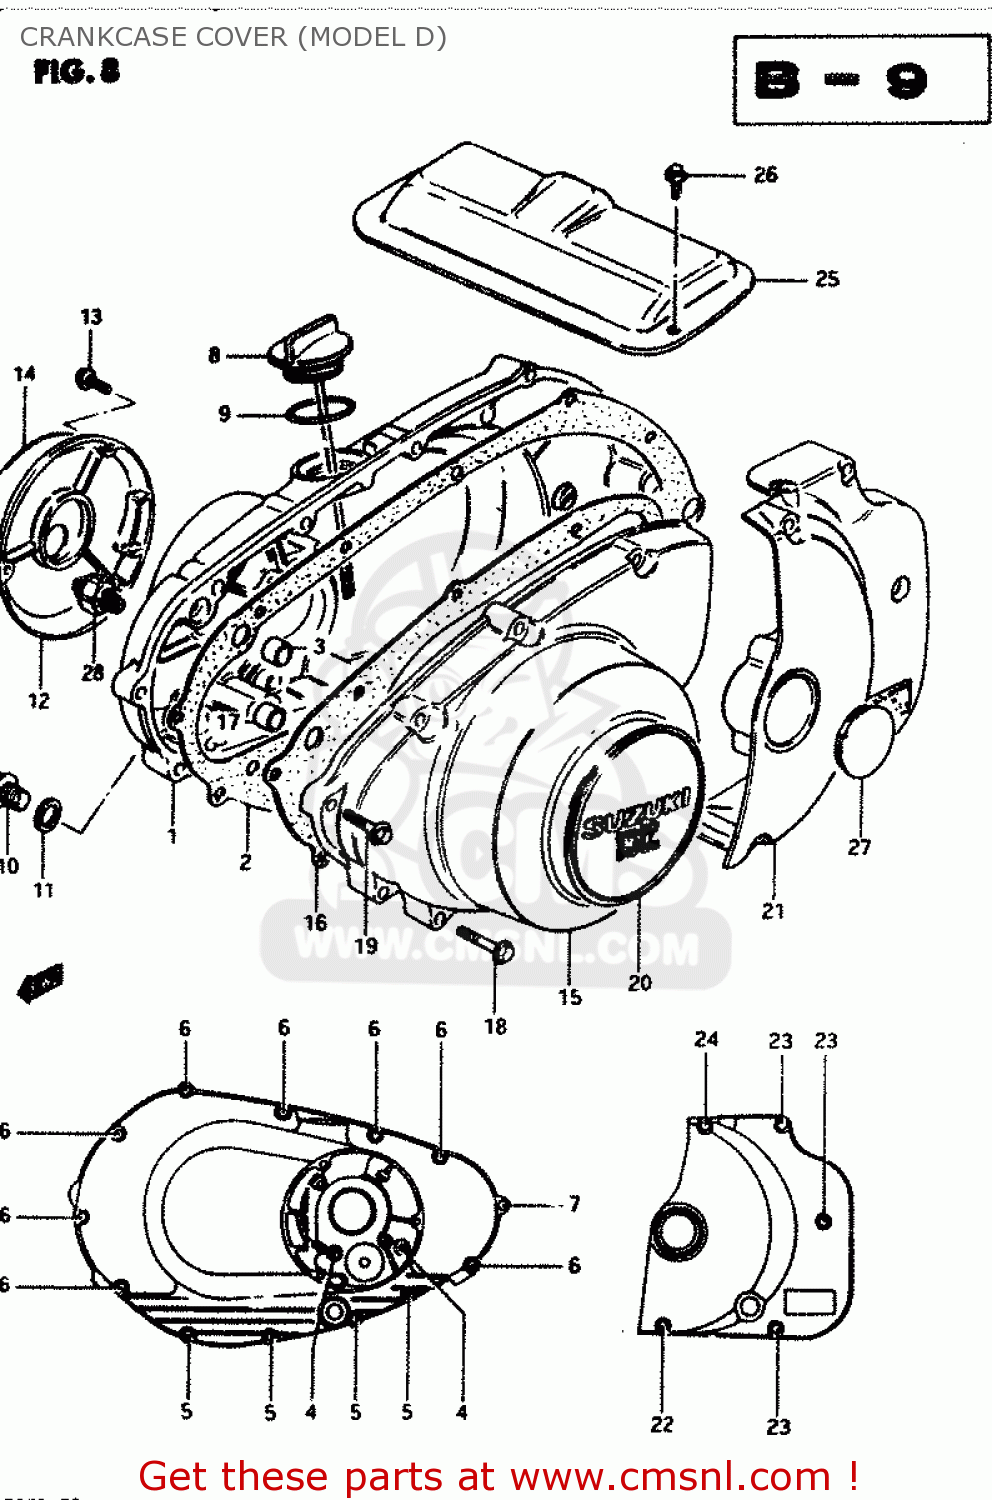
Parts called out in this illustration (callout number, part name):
1	COVER, CLUTCH
2	GASKET,CLUTCH COVER (MCA)
3	PIN
4	BOLT 6X50
5	BOLT
6	BOLT 6X35
7	BOLT 6X25
8	GAUGE, OIL LEVEL
9	O-RING
10	PLUG (14X12)
11	GASKET(14X19.2X2) (NAS)
12	COVER, CONTACT BREAKER
13	BOLT
14	EMBLEM
15	COVER, GENERATOR
16	GASKET,MAGNETO COVER (MCA)
17	PIN
18	BOLT 6X30
19	BOLT 6X25
20	EMBLEM
21	COVER, ENGINE SPROCKET
22	BOLT (6X60)
23	BOLT 6X40
24	BOLT 6X30
25	COVER,STARTER MOTOR
26	BOLT
27	CAP(OD:36)
28	SWITCH ASSEMBLY
